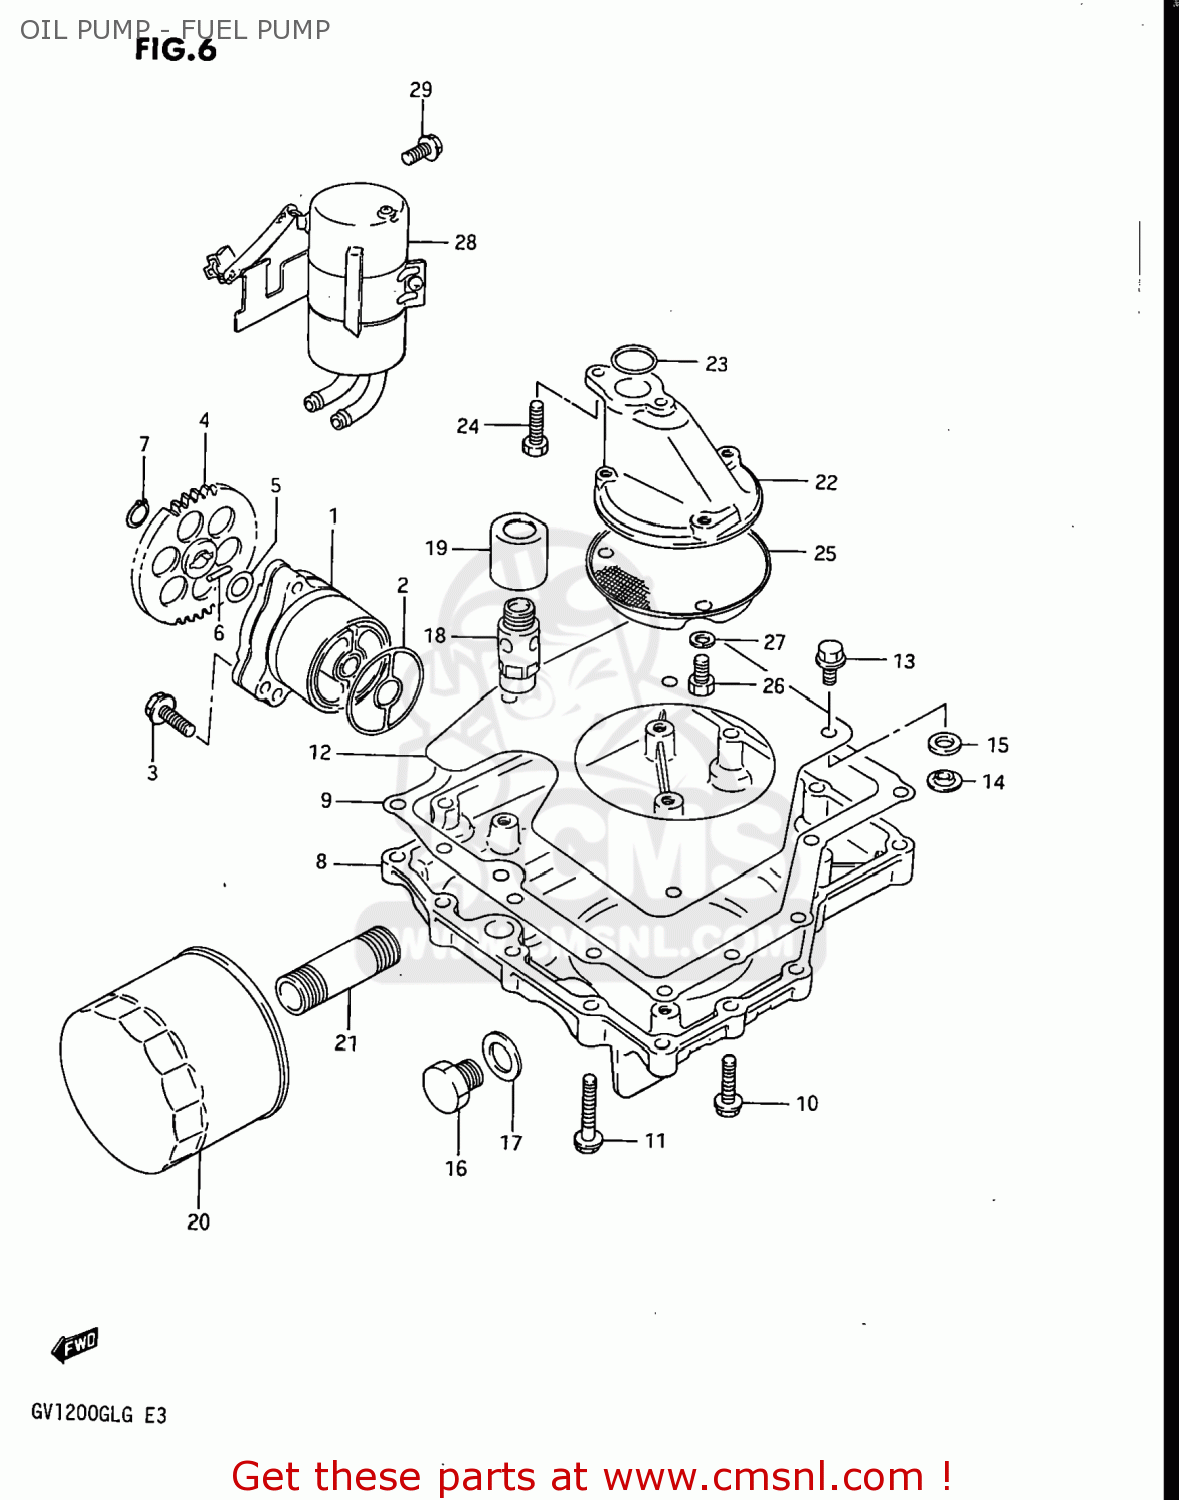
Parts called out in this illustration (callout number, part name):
1	PUMP ASSEMBLY,ENGINE OIL
2	O RING,OIL PUMP
3	BOLT
4	GEAR,OIL PUMP DRIVEN
5	SHIM
6	PIN(4X15.8)
7	CIRCLIP
8	PAN,OIL
9	GASKET,OIL PAN (MCA)
10	BOLT
11	BOLT
13	BOLT
14	CUSHION
15	WASHER
16	PLUG
17	GASKET(14X19.2X2) (NAS)
18	REGULATOR ASSEMBLY,ENGINE
19	GUIDE,OIL RV
20	FILTER ASSY,ENGINE OIL
21	UNION,OIL STAND
22	PROTECTOR,OIL STRAINER
23	O RING(D:3.2,ID:17.8)
24	BOLT,REAR
25	STRAINER,ENGINE OIL
26	BOLT
27	LOCK WASHER
28	PUMP ASSY,FUEL
29	BOLT
